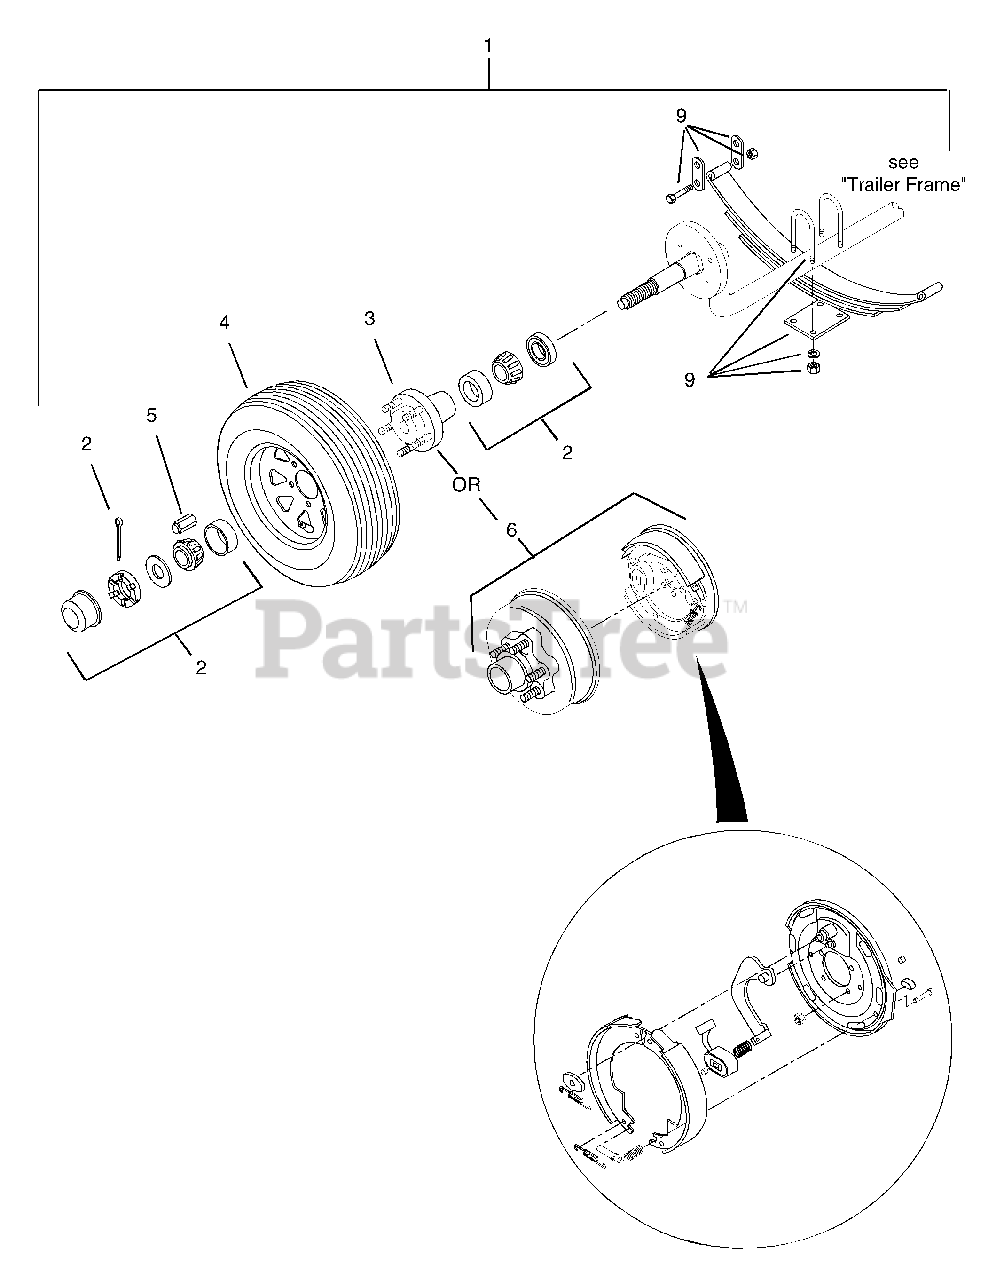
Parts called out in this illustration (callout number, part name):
1	Axle-Complete (Idler)
1	Axle-Complete (Electric Brake)
2	Bearing Kit-Axle Standard
3	Hub-Axle (Idler)
4	Tire/Wheel Assembly
5	Nut-Lug .50-20
6	Kit-Hub-Drum (Electric Axle)
7	Spring-Axle-Standard
8	Kit-Hardware
9	Kit-U-Bolt 3500# Axle Standard
